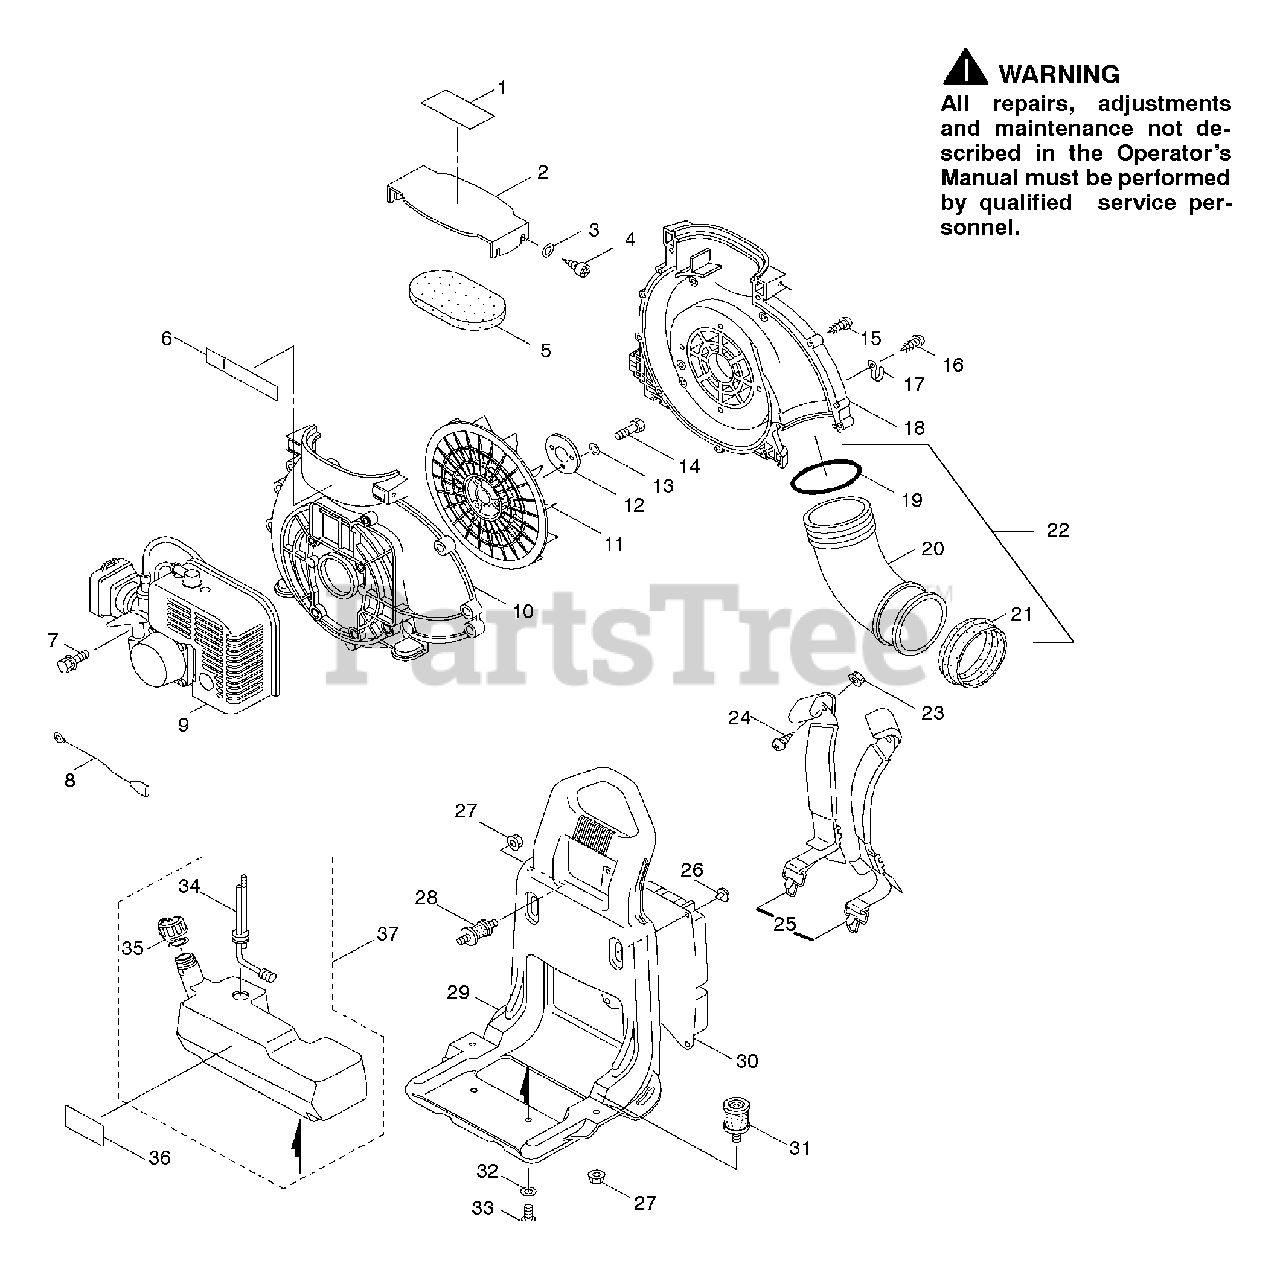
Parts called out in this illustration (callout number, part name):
1	Label - Model/Inst. (Not a serviceable part)
3	Washer - Cover screw
4	Screw - Cover
6	Label - Warning (Not a serviceable part)
8	Ground Wire
9	Shroud
10	Fan Housing - Rear
11	Impeller
12	Plate - Impeller
13	Washer - Spring
15	Screw - Fan Housing
16	Screw - Clamp
18	Fan Housing-Front
19	O-Ring (large)
20	Tube - Blower Outlet
21	Joint - Rubber
22	Kit-Tube & O-Ring
25	Assy. - Shoulder Strap
26	Fastener - Pad
28	Isolator - Top
30	Pad - Cushion
31	Isolator - Bottom
34	Fuel Filter Assy.
35	Fuel Cap Assy.
36	Label-Fuel (Caution) (Not a serviceable part)
37	Fuel Tank Assy.
